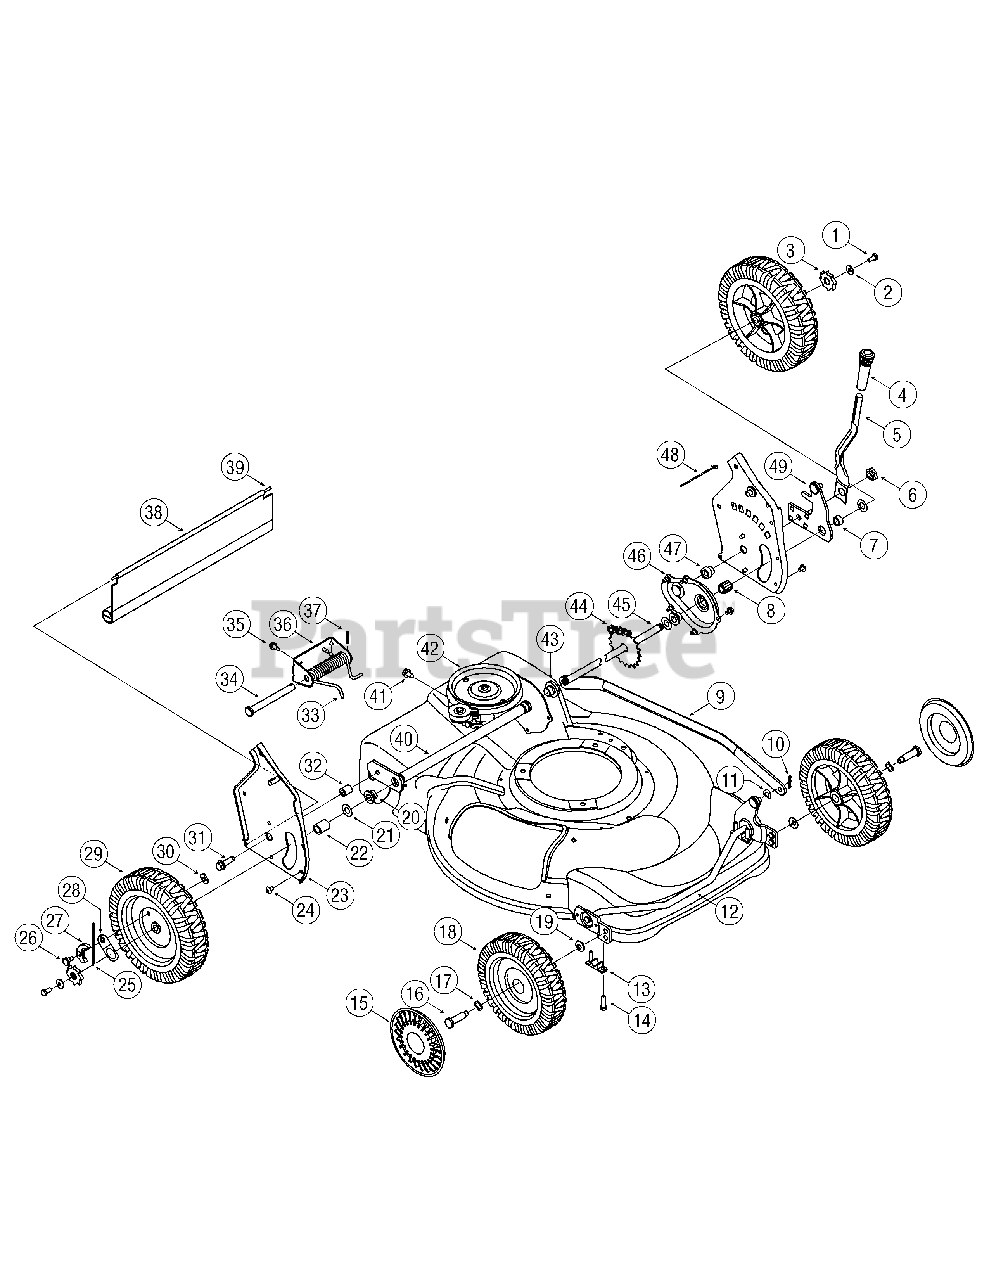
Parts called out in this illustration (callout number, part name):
1	HH Cap Screw 1/4-20 x .620
2	Bell Washer .265 x .75 x .062
3	Wheel Ratchet
5	Spring Lever
6	Shoulder Nut
7	Spacer .51 x .70 x .38
8	Hex Sleeve Bearing
10	Hairpin Clip
11	Bowed Washer
13	Block Bushing
14	Hex Screw 1.4 x 1
15	Hubcap
16	Shoulder Screw .498x1.445x3/8-16
17	Wave Washer .510 x .750 x .017
18	Front Wheel 8 x 2.125 Idle BB Zrk
19	Bell Washer .375 x .870 x .063
20	Hex Flange Bearing
21	Flat Washer .508 x 1 x .020
22	Spacer .550 x .755 x 1.1
25	Plastic Ratchet Spring
26	Shoulder Screw .340x.285x1/4-20
27	PAWL LH
28	Ratchet PAWL Plate
29	Rear Wheel 9 x 2.125 Rwd
31	TT Screw 3/8-16 x 1.25
32	Spacer .385 x .625 x .700
33	Torsion Spring RH
34	Clevis Pin .500 x 4.62
35	TT Screw 1/4-20 x .625
38	Trailshield
39	Trailshield Wire
41	TT Screw 5/16-18 x .625
42	Transmission
43	Hex Flange Bearing
44	Chain
45	Axle Assembly RR
48	Cable Tie
